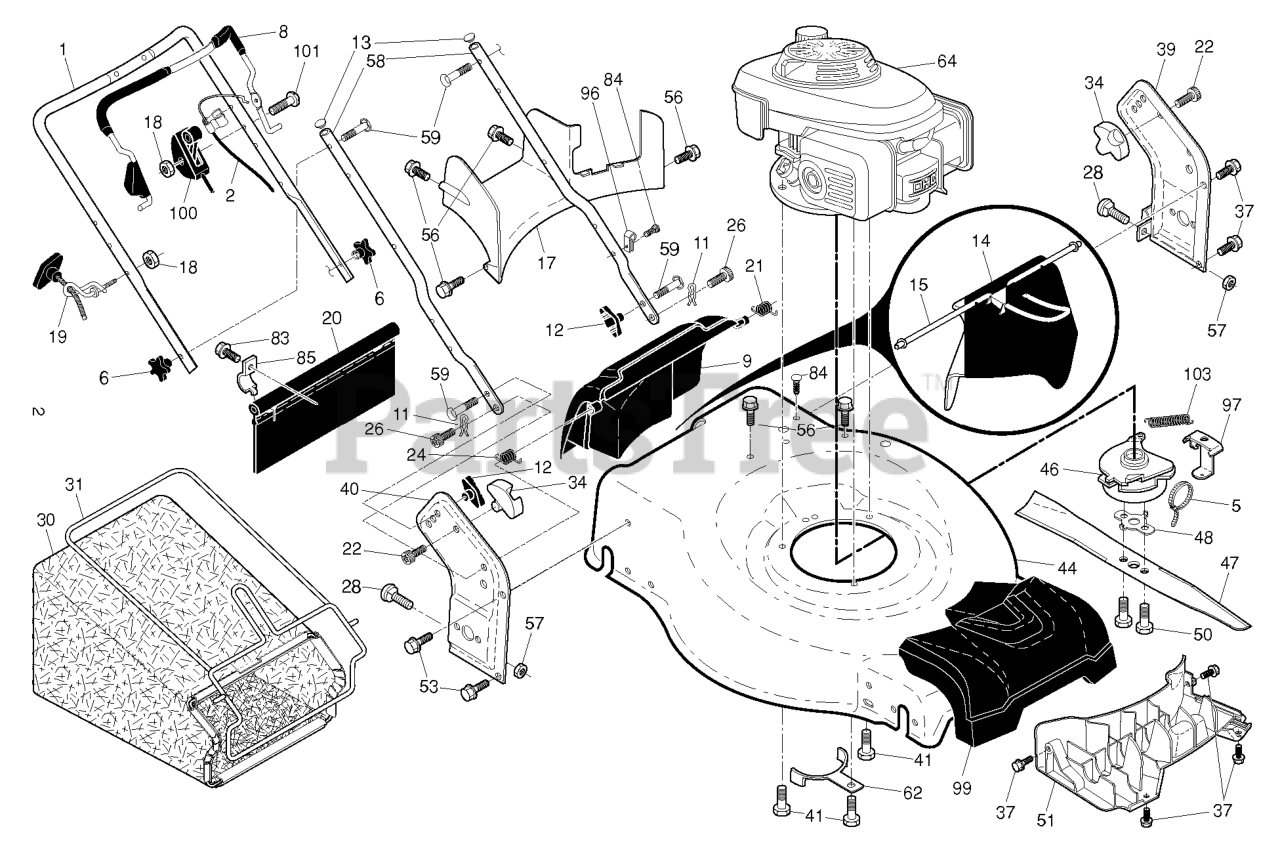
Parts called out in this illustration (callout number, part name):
1	HANDLE.UPPER.3.POS.BS.AW2.GREY
2	CABLE.BBC.HONDA.NO.RDI.22+
6	KNOB.HANDLE.PLASTIC.STAR.BLACK
8	LEVER.ASM.BBC.HONDA.ERGO.OM.O
9	DOOR.REAR.ASM.22+.HUSQ.FG/RGD
11	COTTER.HAIRPIN.DOOR/HANDLE.PIV
12	KNOB, DEFLECTOR
13	PLUG.PLASTIC.7/8".14-20.GAUGE
14	DEFLECTOR.CHUTE.22+REAR
15	HANDLE DEFLECTOR.22+REAR
17	BAFFLE.REAR.22+RGD.AWD.PLASTIC
18	NUT
19	RB GUIDE.ROPE.STD.BLK.ZIN WSL
20	SKIRT.REAR.22PLUS.RGD.LW(2 2MC
21	SPRING.LH.BLACK
22	SCREW.PAN.HEAD.#10
24	SPRING.RH.GRAY
26	SCREW,DOOR/HANDLE.PIVOT
28	BOLT
30	GBAG.BA85028ER.GRY/ORG
31	RB FRAME.GBAG.22PLUS
34	BRACKET.GRASSBAG.ATTACHING.BLK
37	BOLT.5/16HEX.WHS.HD
39	BRACKET.ASM.HNDL.LT.22+.GREY
40	BRACKET.ASM.HNDL.RT.22+.GREY
41	BOLT 3/8-16X1-1/8
44	HOUSING.22+.RWD.HD.WO/PORT.ORA
47	BLADE.3N1.22+W/HONDA.BBC.PREM
48	SPACER.BLADE.HONDA.BBC
50	BOLT.BLADE
51	BAFFLE.FRONT.22+PLASTIC.(2 2)
53	SCREW.HI-LO.5/16 X.75
56	SCREW.HX.13X.750
57	NUT.FLANGE.5/16
58	HANDLE.LOWER.22+BT.2PC.GRY
59	BOLT, HANDLE 5/16-18X1.75
62	BRACKET.KEEPER.BELT
83	TAPPING SCREW
84	FASTENER.PUSH.O.250X0.783
85	BRACKET.SKIRT.22+.BZP
96	CLIP.CABLE.BLK
97	BRACKET.ASM.BBC.MOUNTING.BZP
99	COVER.ASM.FRONT.SHROUD.HUSQ.
100	CONTROL.THROTTLE.HOND.BBC.58.5
103	SPRING.BBC
